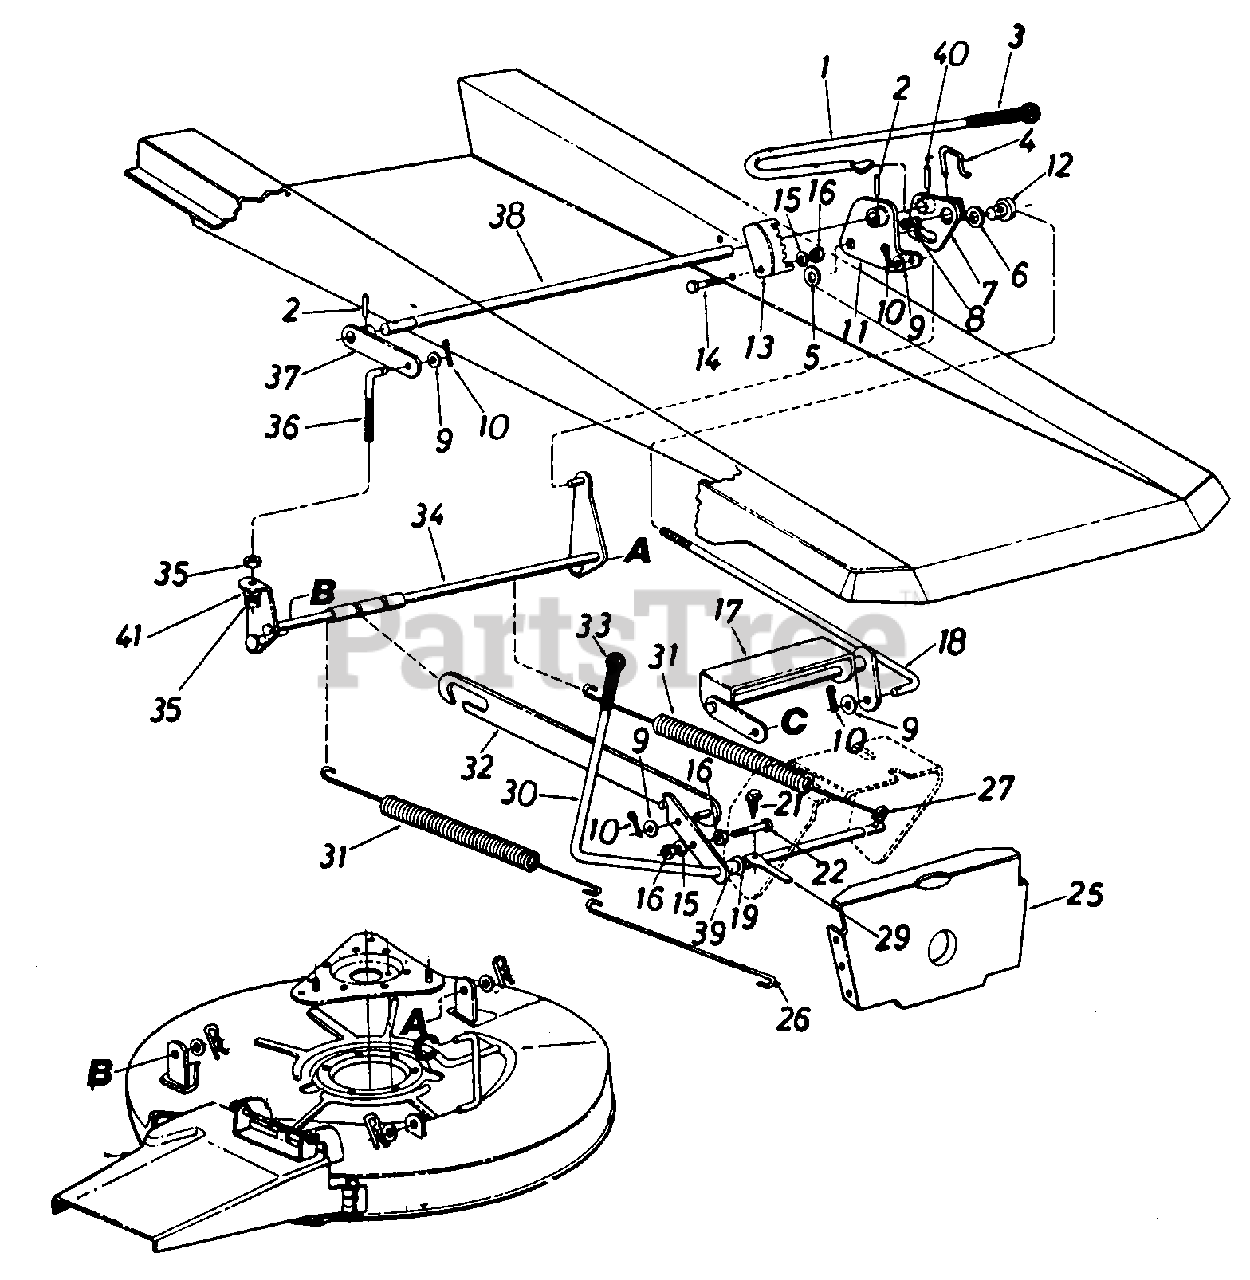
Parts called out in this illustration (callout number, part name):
1	HANDLE-DECK LIFT
2	PIN-SPRING SPIRAL 1/4X1.5 HEAVY DT
5	WASHER-FL-.635 ID X .93 OD
6	WASHER-FL-.640ID X 1.24OD X .06HDN
7	BRACKET ASSY-LIFT
8	SPRING-COMPRESSION
9	WASHER-FL-.385 ID X .87 OD X .06
10	PIN-COTTER-1/8 DIA X 1.00
11	BRACKET ASSY-LIFT-LH
13	BRACKET-INDEX
14	SCREW-HEX 5/16-18 X .75
15	WASHER-LOCK-5/16
16	NUT-HEX 5/16-18
17	LIFT ASSY-DECK-FR
18	ROD-CONNECTING
19	WASHER-FL-.531 X .930 OD X .050
21	SCREW-HEX WASH SF TAPP
22	SCREW-HEX
25	BRACKET-PIVOT BAR
26	SPRING-HOOK
27	PIN-CLEVIS
29	ACTUATOR-SWITCH
30	LEVER ASSY-BLADE ENG
31	SPRING-EXTENSION
32	BRACKET ASSY-DECK DR
34	LINK ASSY-RR
35	NUT-HEX 3/8-16
36	SCREW-DECK ADJ 3/8-16 THD
37	BRACKET ASSY-LIFT-RH
38	SHAFT-HGT ADJ-RR
40	PIN-SPRING SPIR 3/16 X 1.50
41	WASHER-LOCK-3/8
